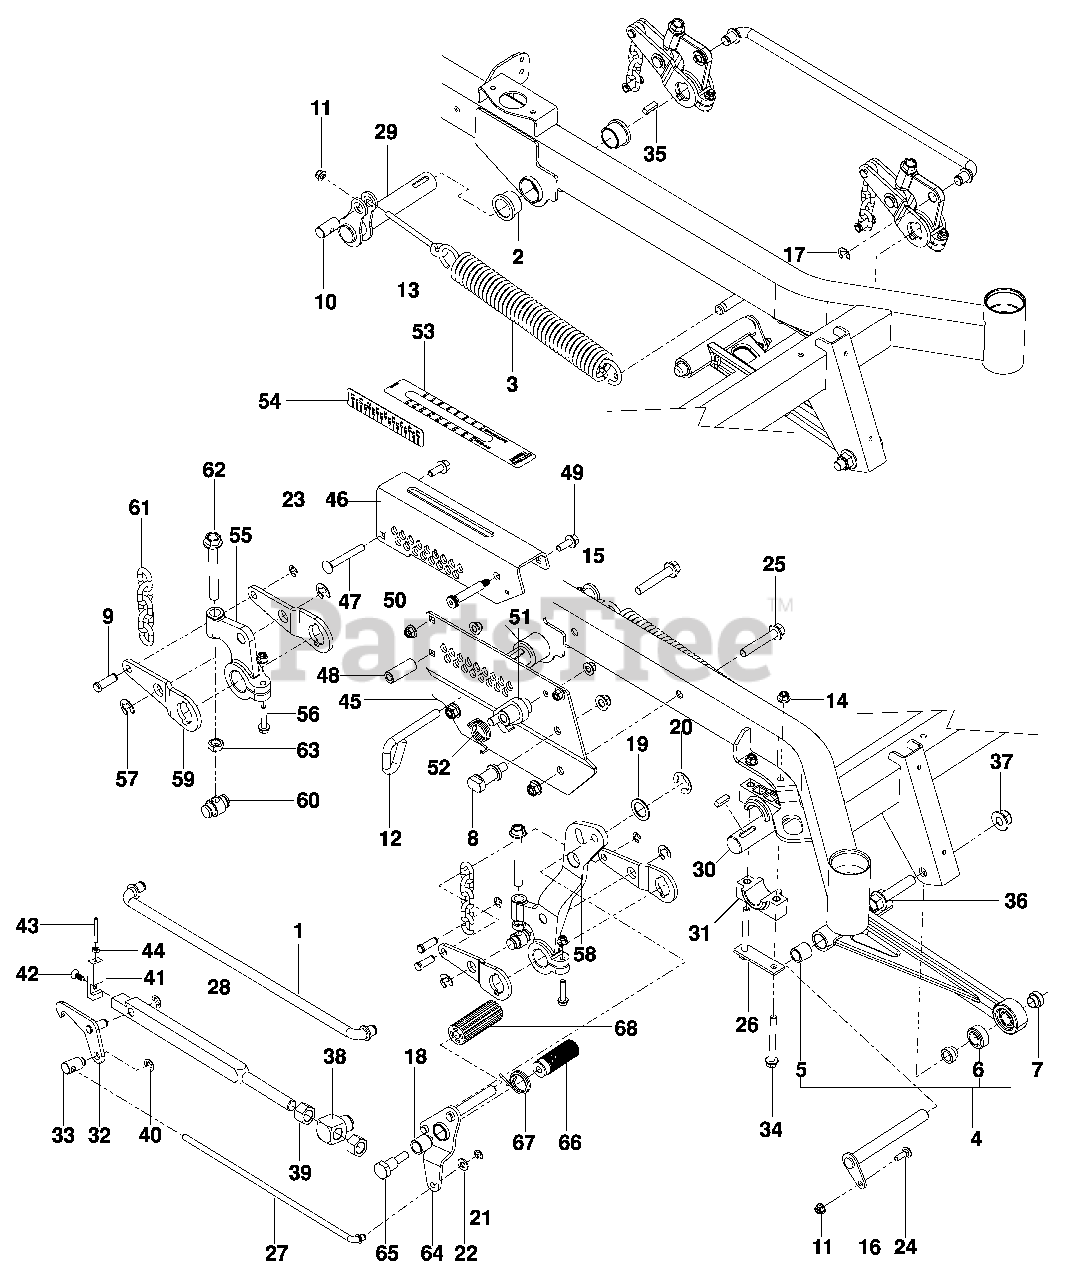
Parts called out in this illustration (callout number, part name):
1	ROD, LIFT
2	BUSHING, FLANGED 1¼ ID
3	SPRING, EXTENSION
4	STRUT ASSY
5	BUSHING, SLEEVE ¾ x 1
6	BALLJOINT ¾ SWIVEL
7	SPACER, STRUT
8	GUIDE, HEIGHT BAR
9	PIN, 7/16 CLEVIS
10	PIVOT, SPRING
11	NUT 5/16-18 HEX FLG NYLOC
12	PIN, HEIGHT
13	EYEBOLT 4½
14	NUT 3/8-16 HEX FLG NYLOC
15	NUT ½-13 HEX FLG NYLOC
16	PIN, STRUT
17	E-RING 5/8
18	BUSHING, SLEEVE ¾ x 1
19	BUSHING 1" x 14 GA
20	E-RING 1"
21	E-RING 3/8"
22	WASHER, 3/8 SAE FLT
23	RING 7/16"
24	BOLT 5/16-18 x 1 RD HD
25	BOLT ½-13 x 3 HEX FLG
26	PLATE, PILLOW BLOCK
27	ROD, HEIGHT LATCH
28	BAR, HEIGHT
29	SHAFT, RR LIFT
30	SHAFT, LIFT, FT
31	BLOCK, PILLOW
32	LATCH, HEIGHT
33	SWIVEL, HEIGHT LATCH
34	SCREW 3/8-16 x 3½ HEX FLG
35	KEY 5/16 SQ x 1
36	SCREW 5/8-11 x 3 HEX FLG
37	NUT 5/8-11 FLG NYLOC
38	SWIVEL, HEIGHT BAR
39	NUT ¾-10 HEX
40	E-RING ½"
41	CAP, HEIGHT BAR
42	SCREW 5/16-18 x ¾ HEX SCKT
43	LINK, INDICATOR
44	NUT ¼-20 JAM
45	PLATE, INNER HEIGHT
46	PLATE, OUTER HEIGHT
47	BOLT 3/8-16 x 3 RD HD GR2
48	SPACER, HEIGHT PLATE
49	SCREW 3/8-16 x 1 HEX FLG
50	BOLT ½ x 2¼, 3/8-16 SHLDR
51	LATCH, TRANSPORT
52	SPRING, TORSION
53	DECAL, HEIGHT
54	DECAL, HEIGHT
55	ARM, CAST LIFT
56	SCREW 5/16-18 x 1½ HEX FLG
57	E-RING ¾"
58	LEVER, DECK LIFT
60	SHAFT, LIFT TRUNION
61	LIFT CHAIN
62	BOLT ½-13 x 4 HEX TPBLT
63	NUT ½-13 HEX JAM
64	PEDAL, RELEASE
65	BOLT, SHOULDER
66	PAD, FOOT PEDAL
67	SPRING, TORSION
68	PEDAL, DECK HEIGHT
